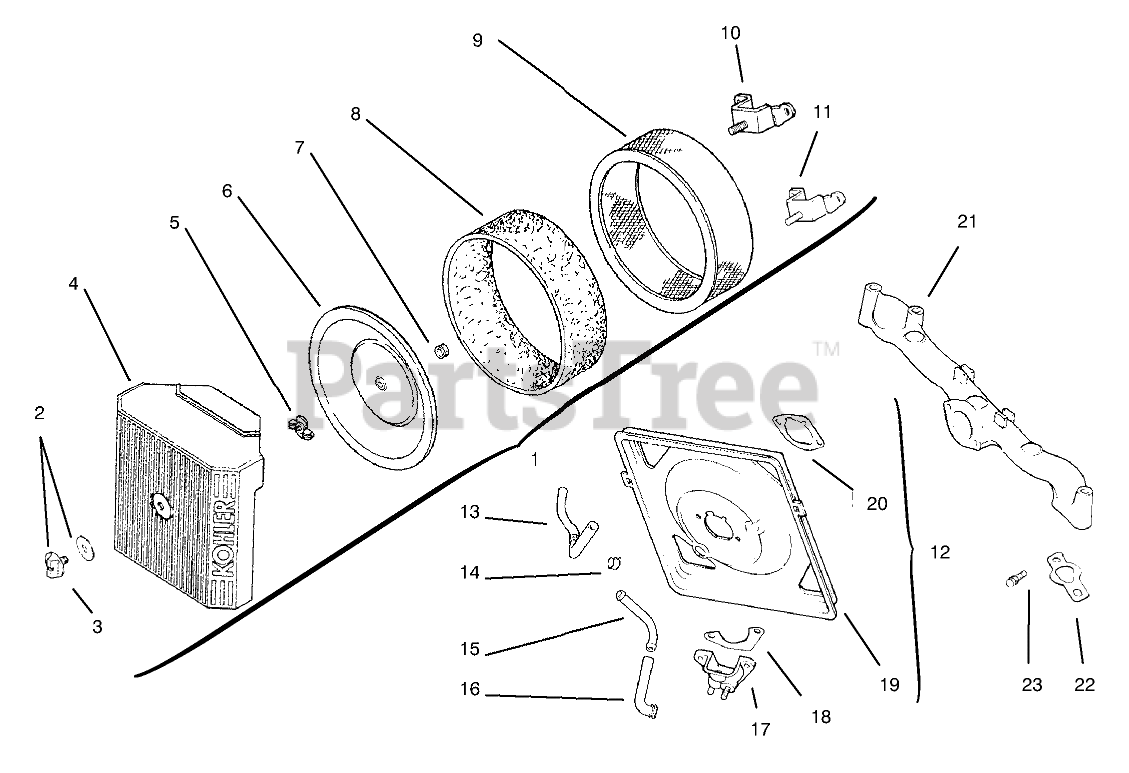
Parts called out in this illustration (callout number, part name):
1	Kit-A/C Cover INC 2-4
2	Spring-Latch
3	Latch-Lever
4	Pin-Latch Lever
5	Wingnut
6	Seal, insert
7	Cover-Inner AirCleaner
8	Bement-Precleaner
9	Bement-Air Cleaner
10	Cup-Fuel Spitback
11	Gasket-Fuel Spitback
12	Base-Air Cleaner
13	Gasket-A/C Base
14	Manifold-Intake
15	Gasket-Intake, Manifold
16	Screw
